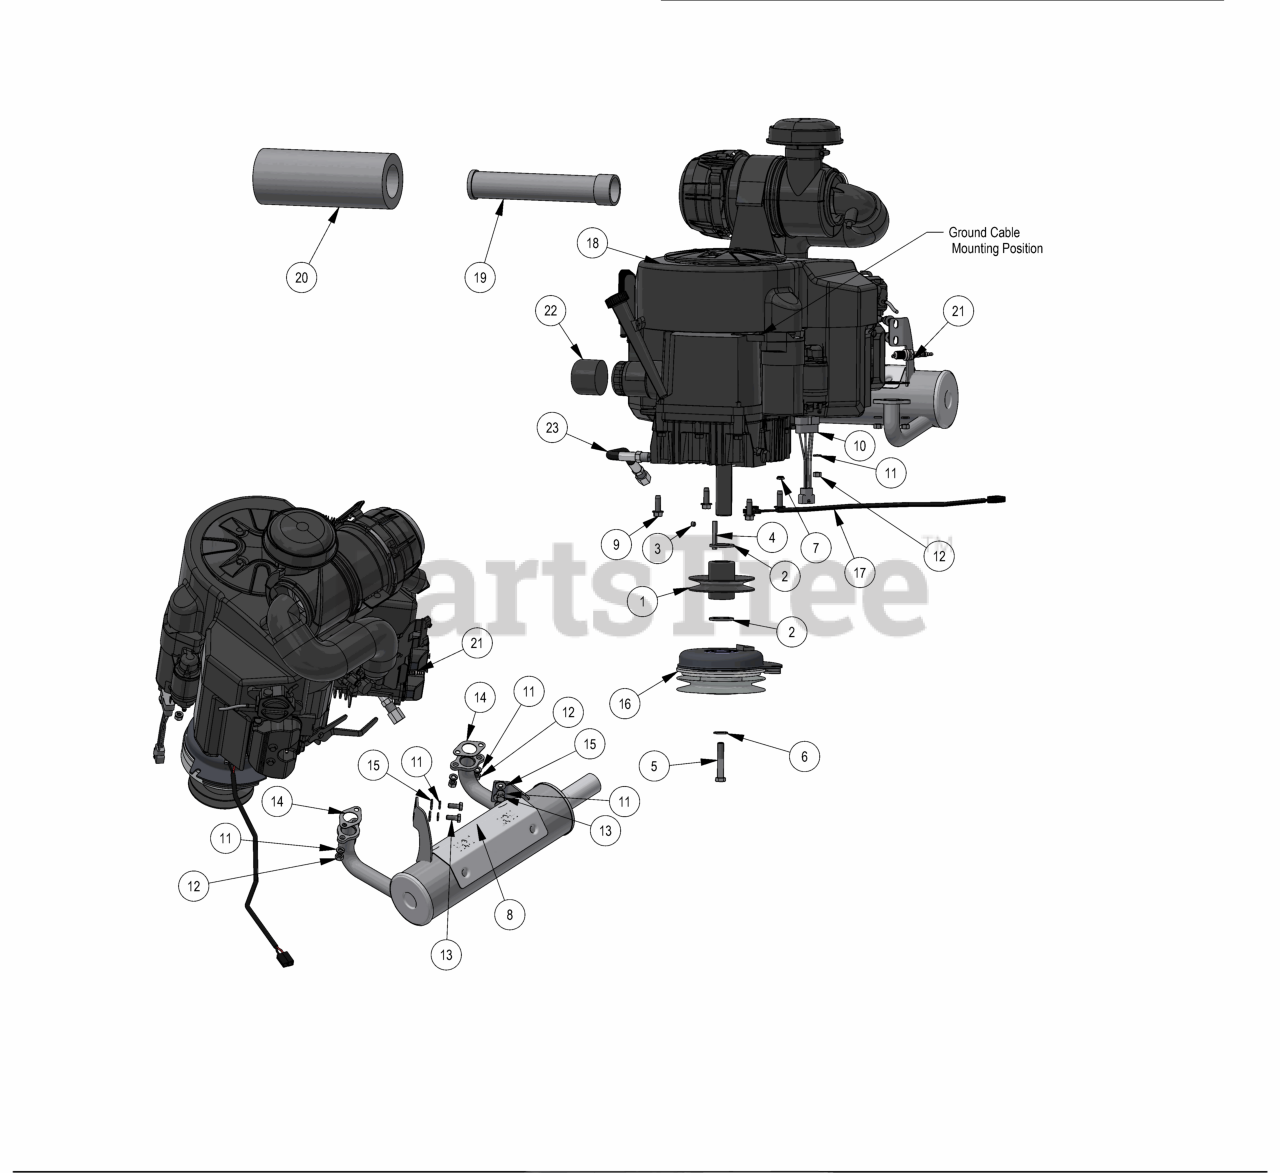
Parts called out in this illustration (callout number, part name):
1	4 3/4 Motor Pulley
2	1.140 ID X 1.750 OD X .132 THICK FLAT WASHER PLAIN
3	5/16-24 X 1/4 SOCKET SET SCREW (CUP PT) PLAIN
4	1/4 X 2 SQ MACHINERY KEY 1018 STL PLAIN
5	7/16-20 X 2-1/2 HEX CAP SCREW (GR.8) ZINC YELLOW
6	3/8 FLAT WASHER USS (1" OD) ZINC
7	5/16-18 NYLON INSERT JAM LOCKNUT ZINC
8	Revolt Kawasaki FX850 Exhaust
9	3/8-16 X 1-1/8HEX WASHER UNSLOT SERRATED (TRI-LOB) TRS
10	2019 Harness Adaptor-Gen2 FX-ALL
11	5/16 SPLIT LOCKWASHER ZINC
12	M8-1.25 DIN 934 HEX NUT (CL.8) ZINC
13	M8-1.25 X 20MM DIN 933 HEX TAP BOLT (CL 8.8) ZINC
14	Exhaust Gasket
15	1/4 USS FLAT WASHER (3/4 OD) ZINC
16	Clutch Assembly
17	Clutch Pigtail
18	Kawasaki Engine FX-850-V-CS09R
19	Canister Air Filter- Inner
20	Canister Air Filter- Outer
21	Spark Plug - Kawasaki
22	Oil Filter
23	Oil drain Hose
